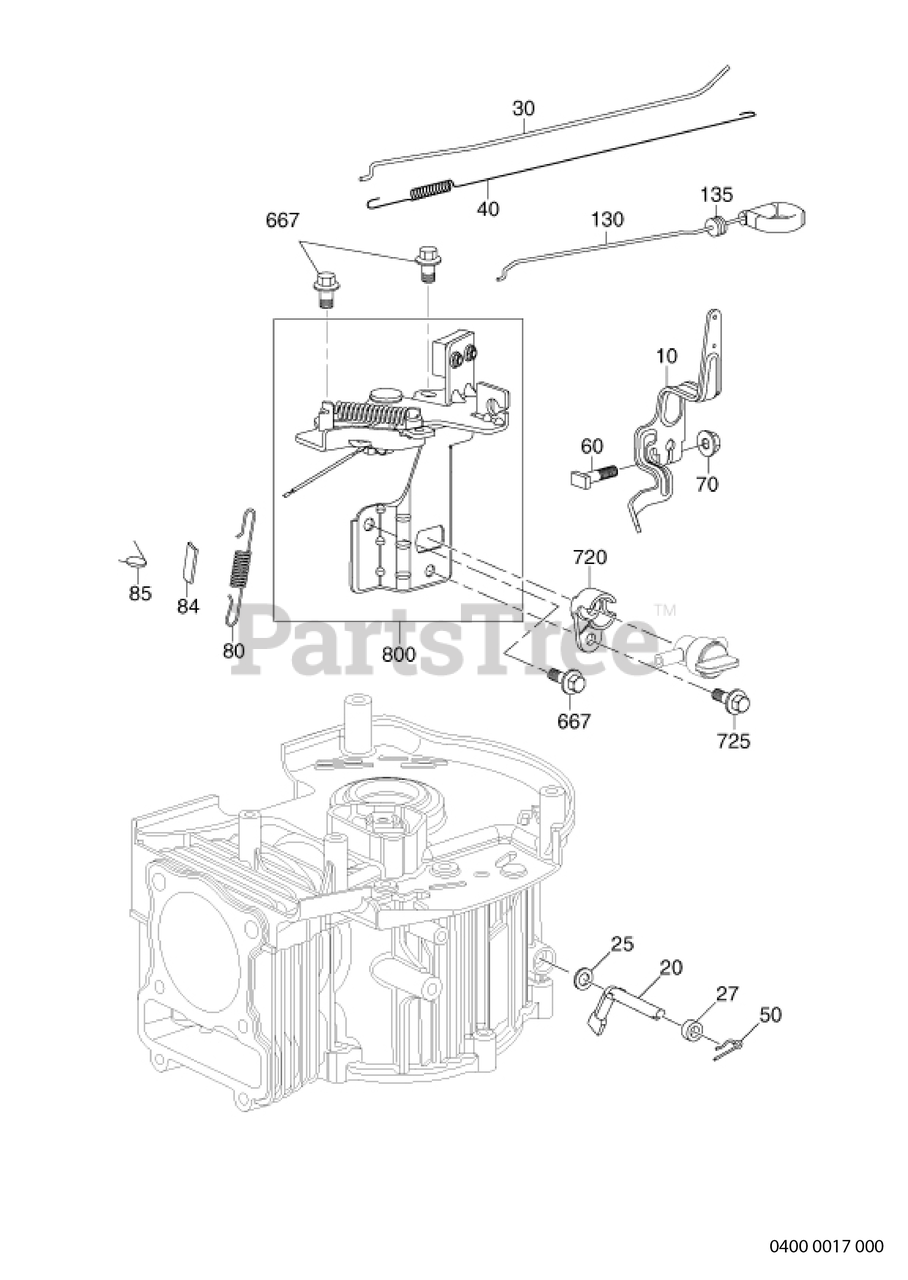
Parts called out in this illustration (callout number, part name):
25	WASHER
27	OIL SEAL
30	THROTTLE CTL LEVER
40	TH RETURNING SPRING
60	BOLT
80	GOVERNOR SPRING
135	CHOKE LEVER HOLDER
667	BOLT
720	FUEL VALVE BASE
725	BOLT
800	BRAKE
